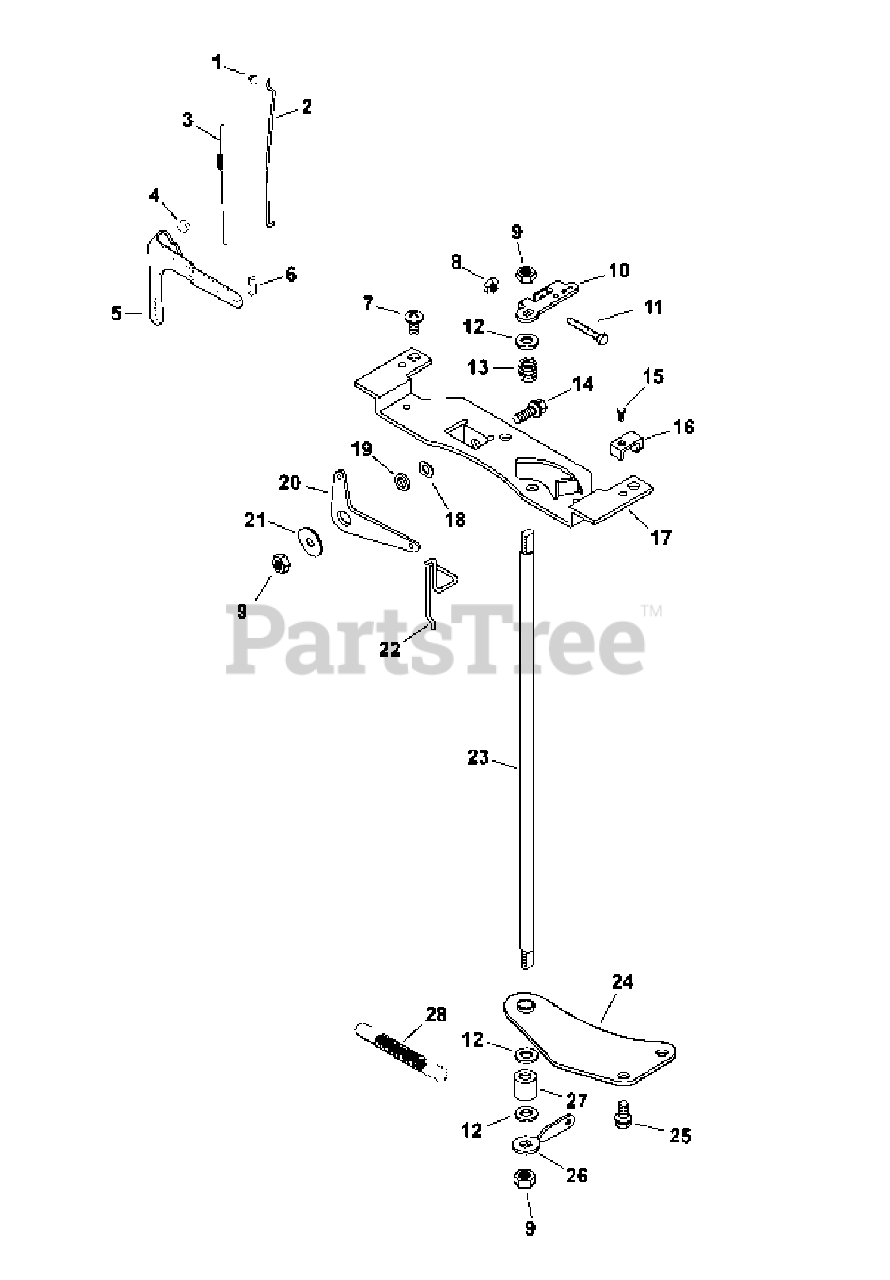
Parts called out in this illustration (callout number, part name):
1	Linkage Retaining Bushing
2	Throttle Linkage
3	Linkage Spring
4	Flange Nut, M6 x 1.0
5	Governor Lever
6	Throttle Linkage Bushing
7	Screw, 11-16 X 3/4
8	Nut, M4 x 0.7
9	Lock Nut, M6 x 1.0
10	Throttle Control Lever
11	Cap Screw, M4 x .7 X 30
12	Flat Washer, 1/4
13	Throttle Shaft Spring
14	Flange Screw, M6 x 1.0 x 16
15	Flange Screw, M5 x 0.8 x 16
16	Cable Clamp
17	Control Bracket
18	Spring Washer, 3/8
21	Flat Washer, 1/4
22	Choke Linkage
23	Throttle Shaft
24	Throttle Shaft Bracket
25	Flange Screw, M6 x 1.0 x 16
26	Throttle Control Lever
28	Governor Spring (Black)
